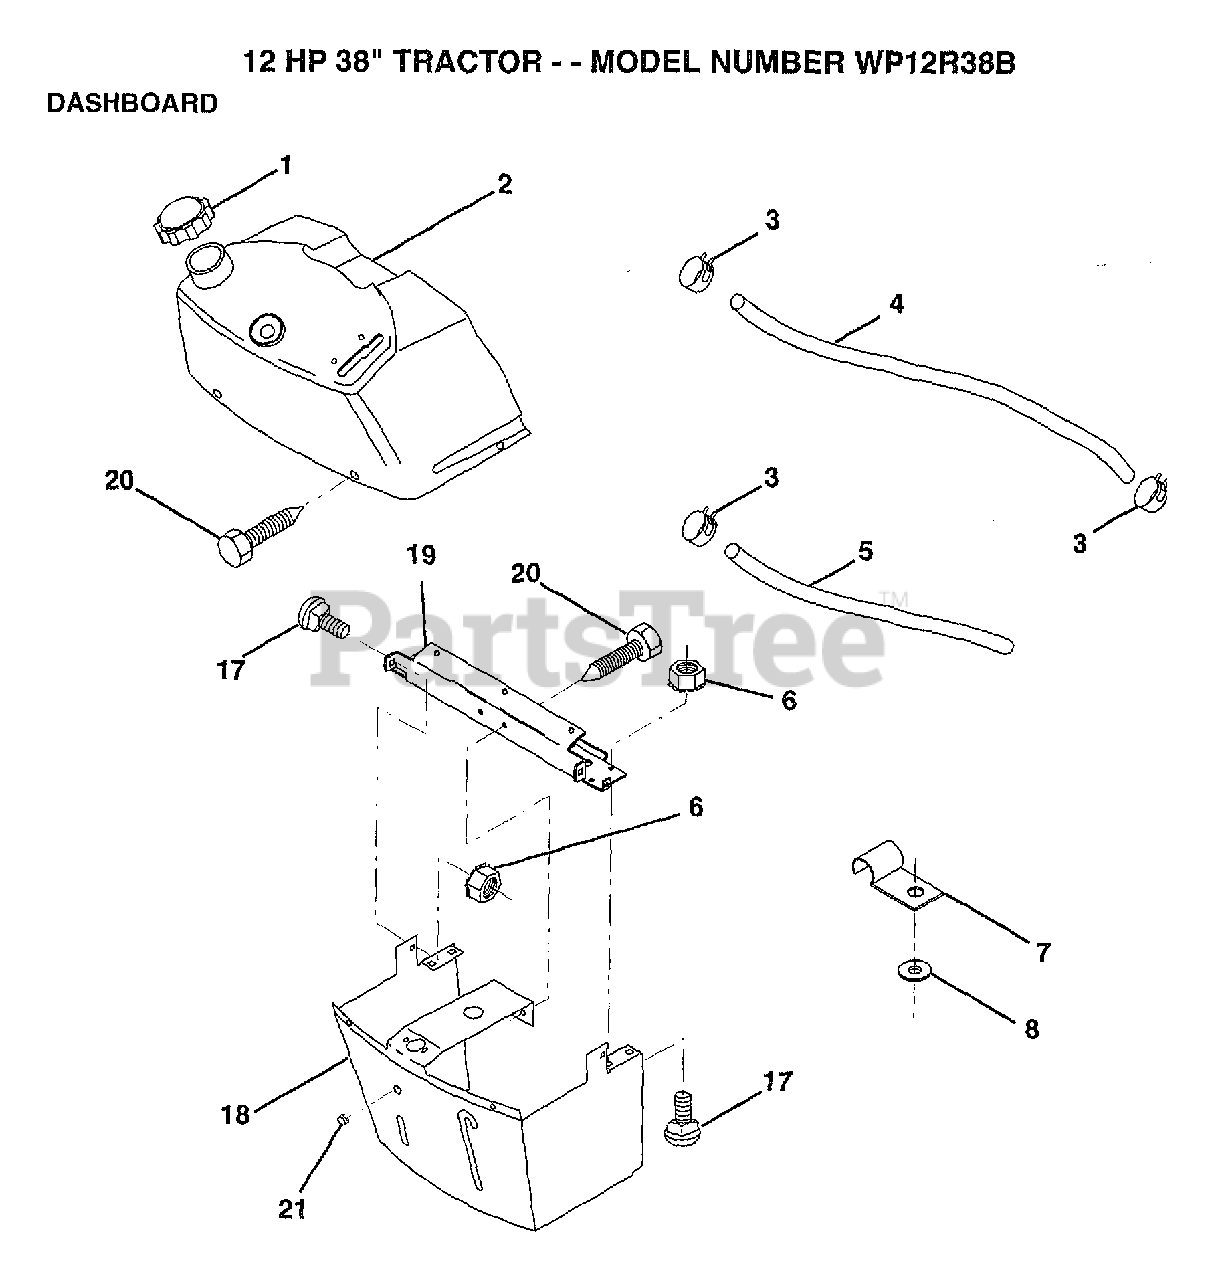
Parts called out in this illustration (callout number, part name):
1	CAP.FUEL.N/VENT
2	TANK.ASM.DASH.LR
3	HOSE CLAMP
5	FUEL LINE T
6	NUT
7	CLIP T
8	WASHER PM
17	BOLT
18	SUPT ASM DASH
19	CROSS BRACE
20	SCREW.1/4-20X1/2
21	PLUG DOME
